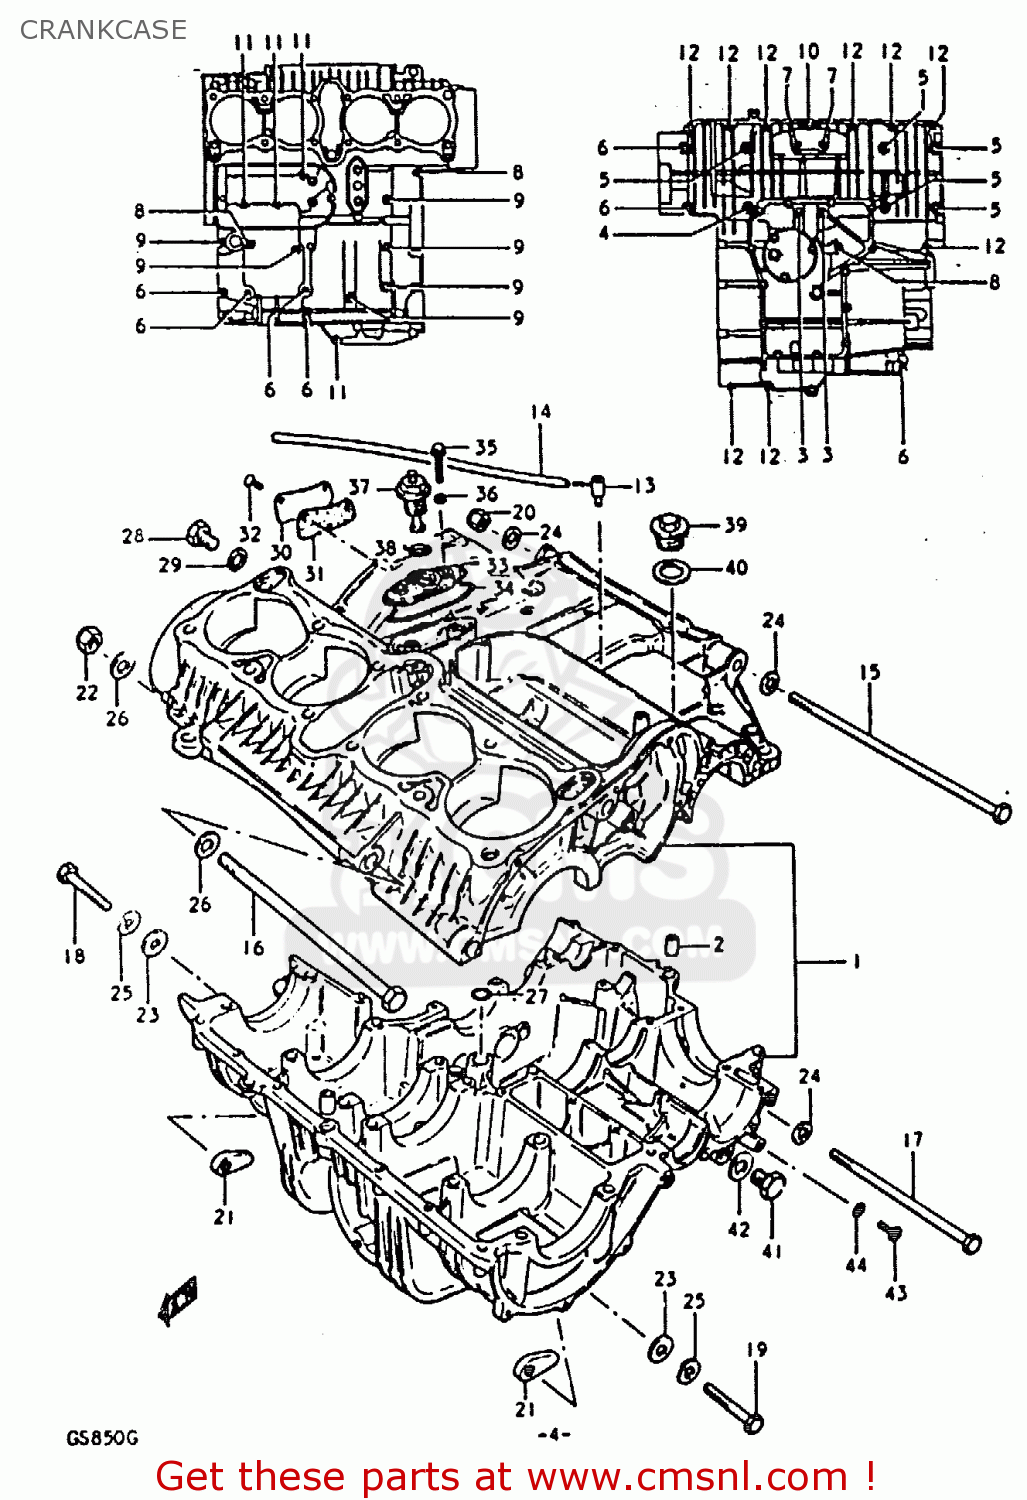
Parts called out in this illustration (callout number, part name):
1	CRANKCASE SET
2	PIN
3	BOLT
4	BOLT
5	BOLT 8X90
6	BOLT 8X65
7	BOLT
8	BOLT (6X90)
9	BOLT (6X75)
10	BOLT ,6X50
11	BOLT,UNDER
12	BOLT 6X35
13	BPLUG,BEVEL GEAR BREATHER
14	HOSE
15	BOLT 10X270
16	SHAFT,REAR SWING ARM
17	BOLT(10X165)
18	BOLT 10X60
19	BOLT (10X50)
20	NUT
21	NUT
22	NUT 12MM
23	WASHER(10.5X20X3.2)
24	WASHER
25	LOCK WASHER
26	WASHER
27	O RING(D:3.2,ID:12.9)
28	PLUG (14X12)
29	GASKET(14X19.2X2) (NAS)
30	CAP,OIL GALLERY
31	GASKET,OIL GALLERY (MCA)
32	SCREW
33	HOUSING,OIL PRESSURE SWITCH
34	O RING,PRESSURE SWITCH HOUSING
35	BOLT
36	GASKET (NAS)
37	SWITCH ASSEMBLY
38	O RING(D:1.9,ID:18.8)
39	PLUG
40	GASKET (NAS)
41	PLUG
42	GASKET(14X19.2X2) (NAS)
43	SCREW(6X10)
44	GASKET (NAS)
